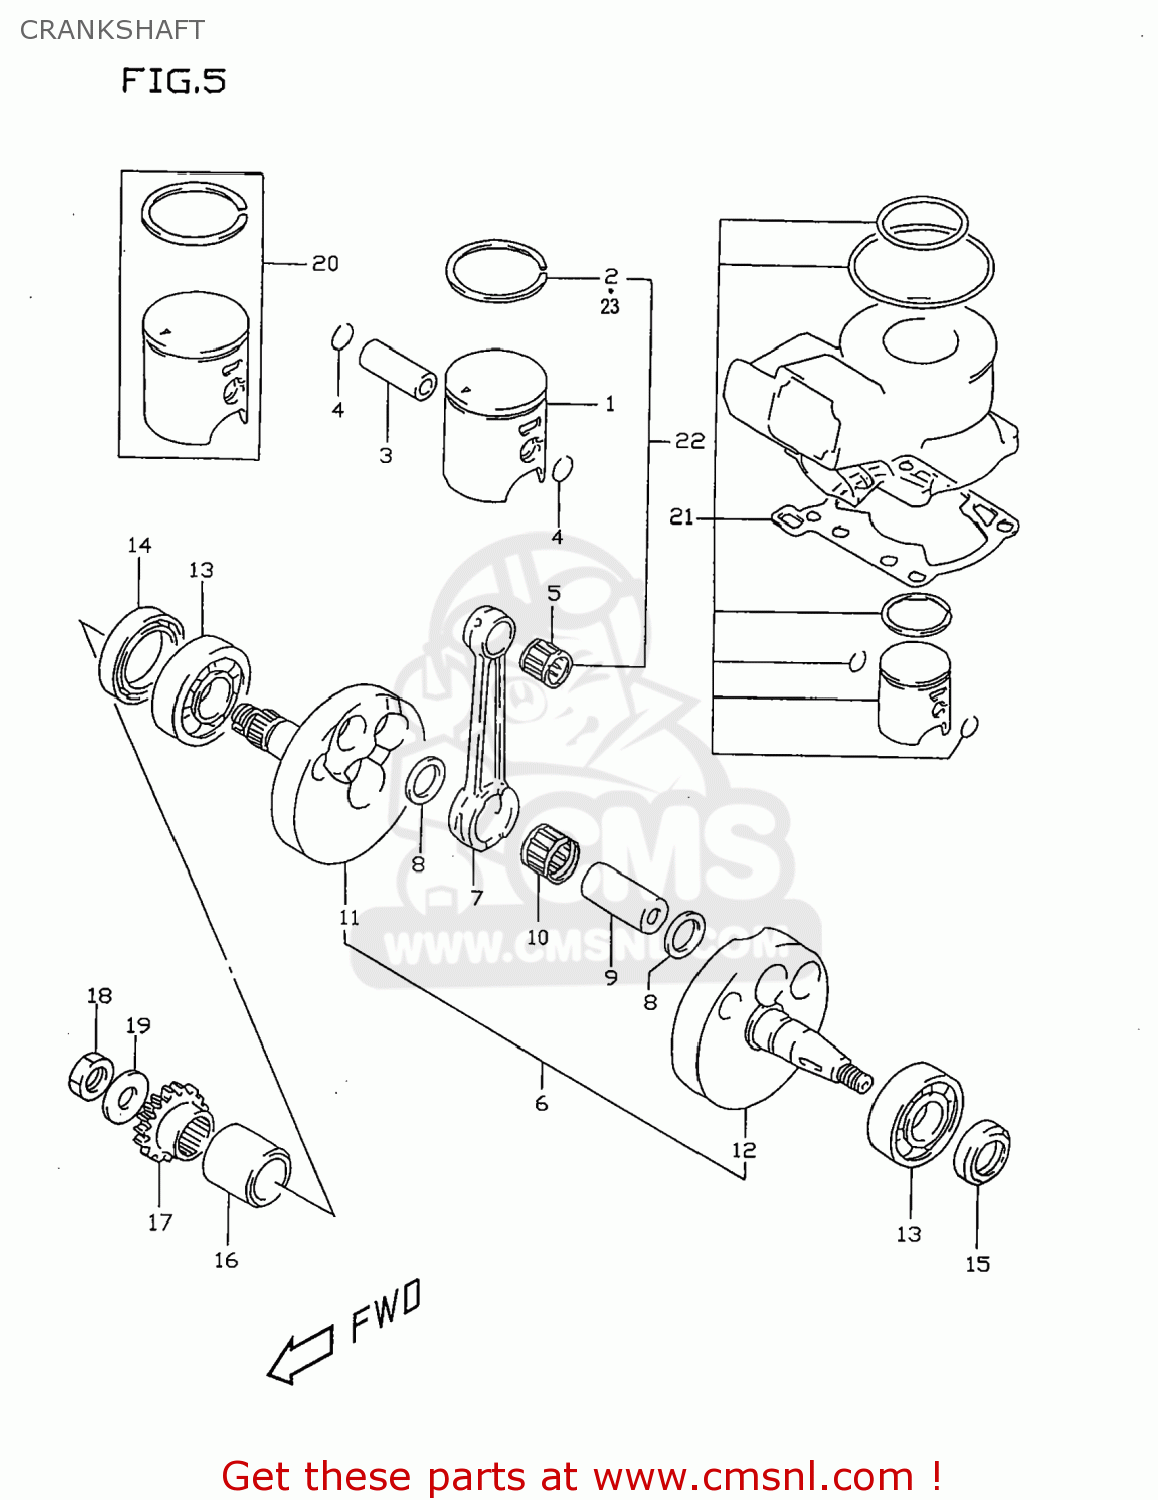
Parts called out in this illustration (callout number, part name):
1	PISTON
2	RING,PISTON
3	PIN,PISTON
4	RING,SNAP 14MM
5	BEARING(14X18X16)
6	CRANKSHAFT ASSY
7	ROD,CONNECTING
8	WASHER
9	PIN,CRANK
10	BEARING(20X26X13.7)
11	CRANKSHAFT,RIGHT
12	CRANKSHAFT,LEFT
13	BEARING(20X52X15)
14	SEAL,OIL(30X40X7)
15	SEAL,OIL(18X30X6)
16	SPACER,PRIMARY DRIVE GEAR
17	GEAR,PRIMARY DRIVE (NT:
18	NUT
19	WASHER
20	PISTON SET(OS:0.5)
21	TOP END KIT,ENGINE
22	PISTON KIT
